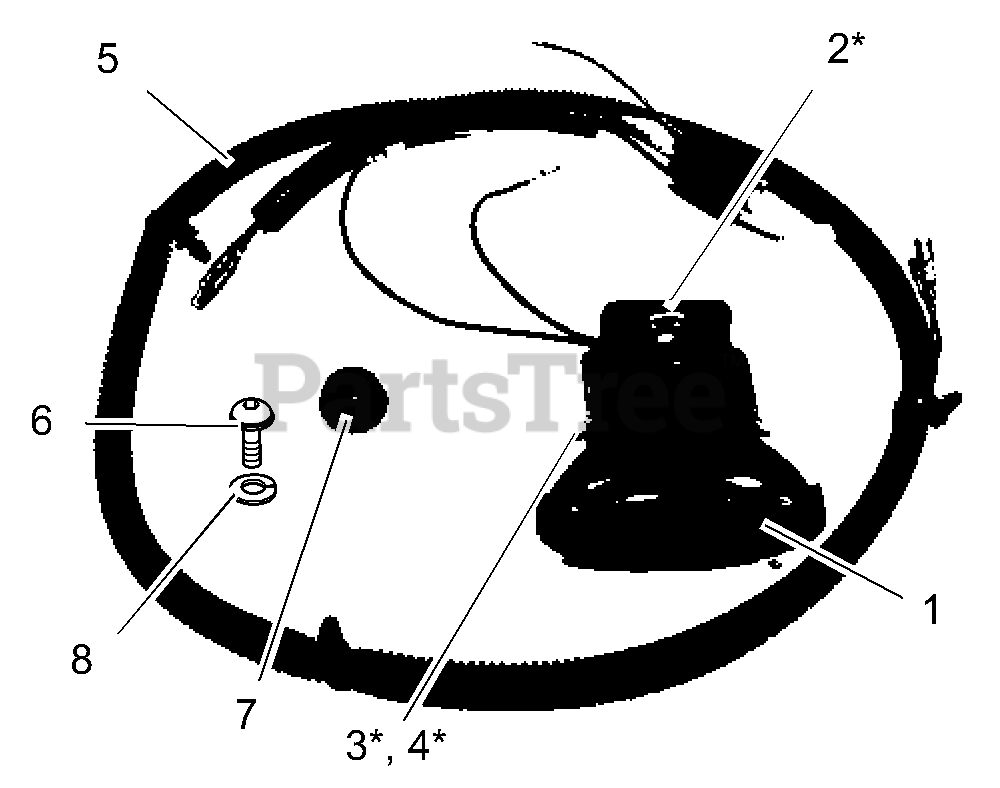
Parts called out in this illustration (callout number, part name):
1	KIT-ZOOM LITE
2	WMT, LIGHT BRACKET
3	WSHR-LK 4MMX1MM REG CL ZINC
4	SCREW-M4X.07X8 SHCS CLZNC
5	HARNESS, LIGHT
6	SCR-CAP BTHD.31-18X.50 GR5 YZ
7	GROMMET, RUBBER 3/8 I.D.
8	@WSHR-LK .31X.078 REG YWZC
